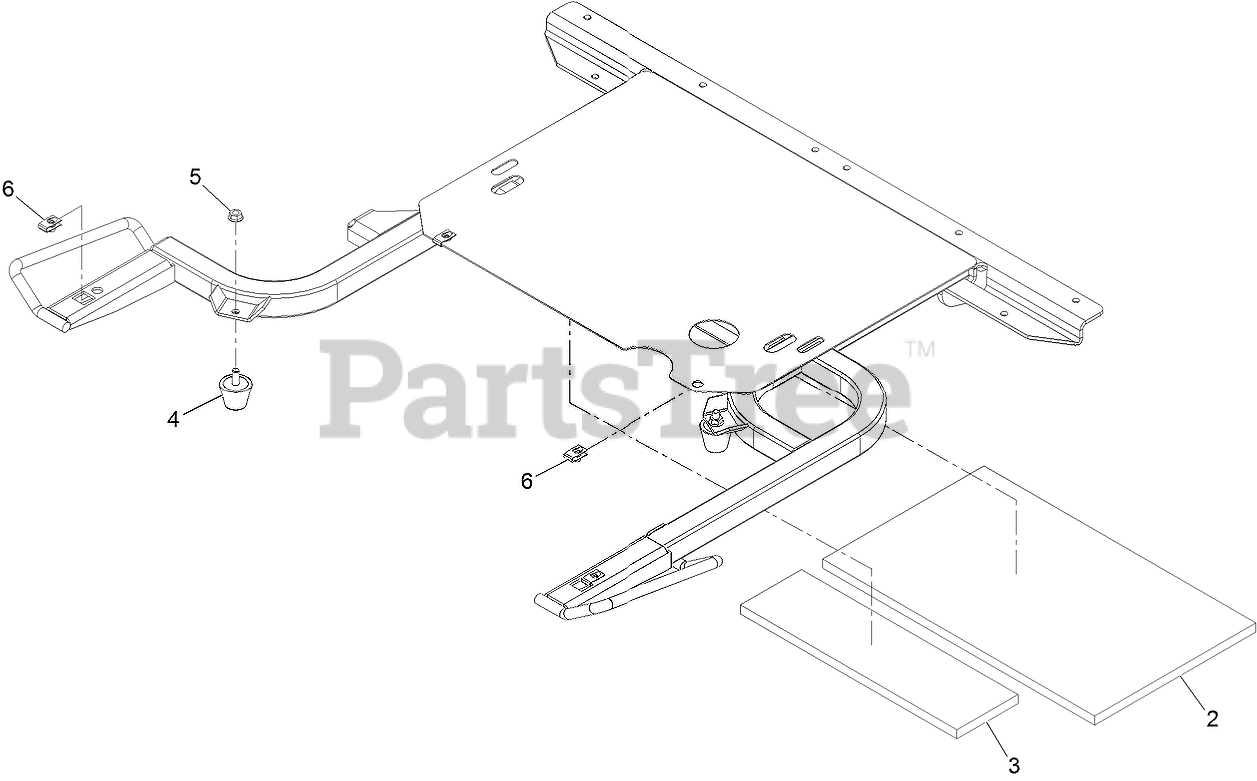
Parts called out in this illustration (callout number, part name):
2	INSULATION-FOAM PAD, REAR
3	INSULATION-FOAM PAD, FRON
4	BUMPER-RUBBER
